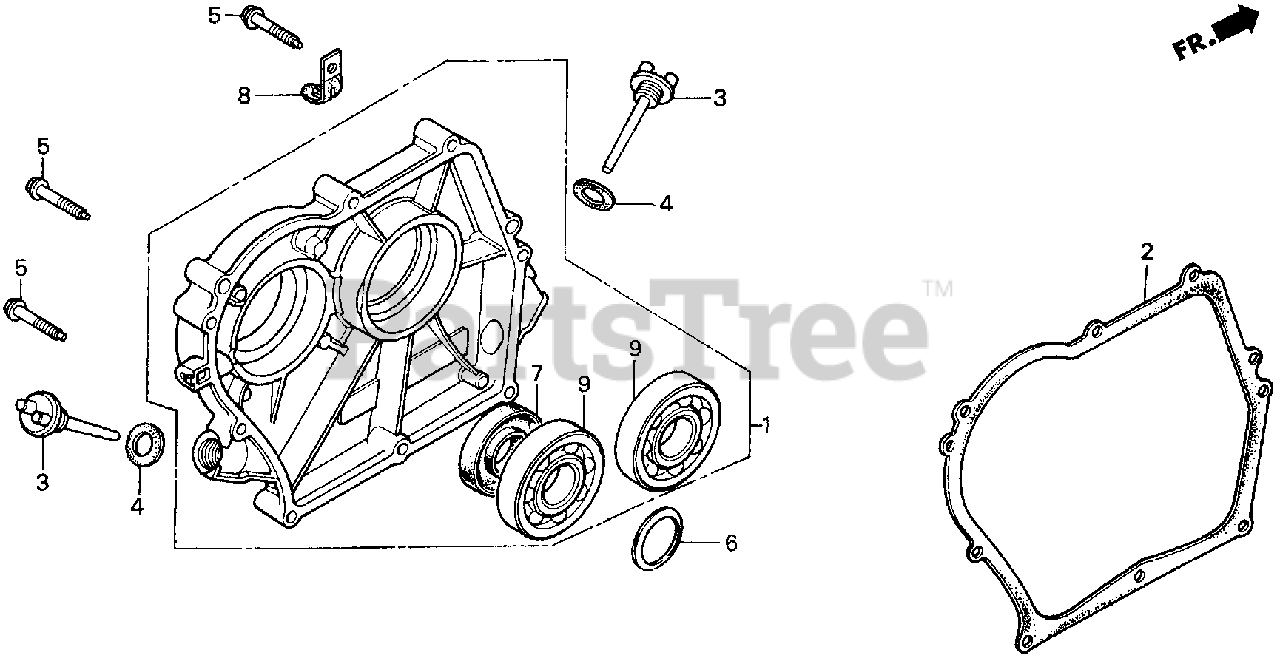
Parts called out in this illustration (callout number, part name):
1	COVER ASSY., CRANKCASE (L-TYPE)
2	GASKET, COVER
4	GASKET, OIL FILLER CAP
5	BOLT, FLANGE (6X32)
6	WASHER, THRUST SPRING
7	OIL SEAL (25X41X6)
8	CLIP, CABLE
9	BEARING, RADIAL BALL (6205)
